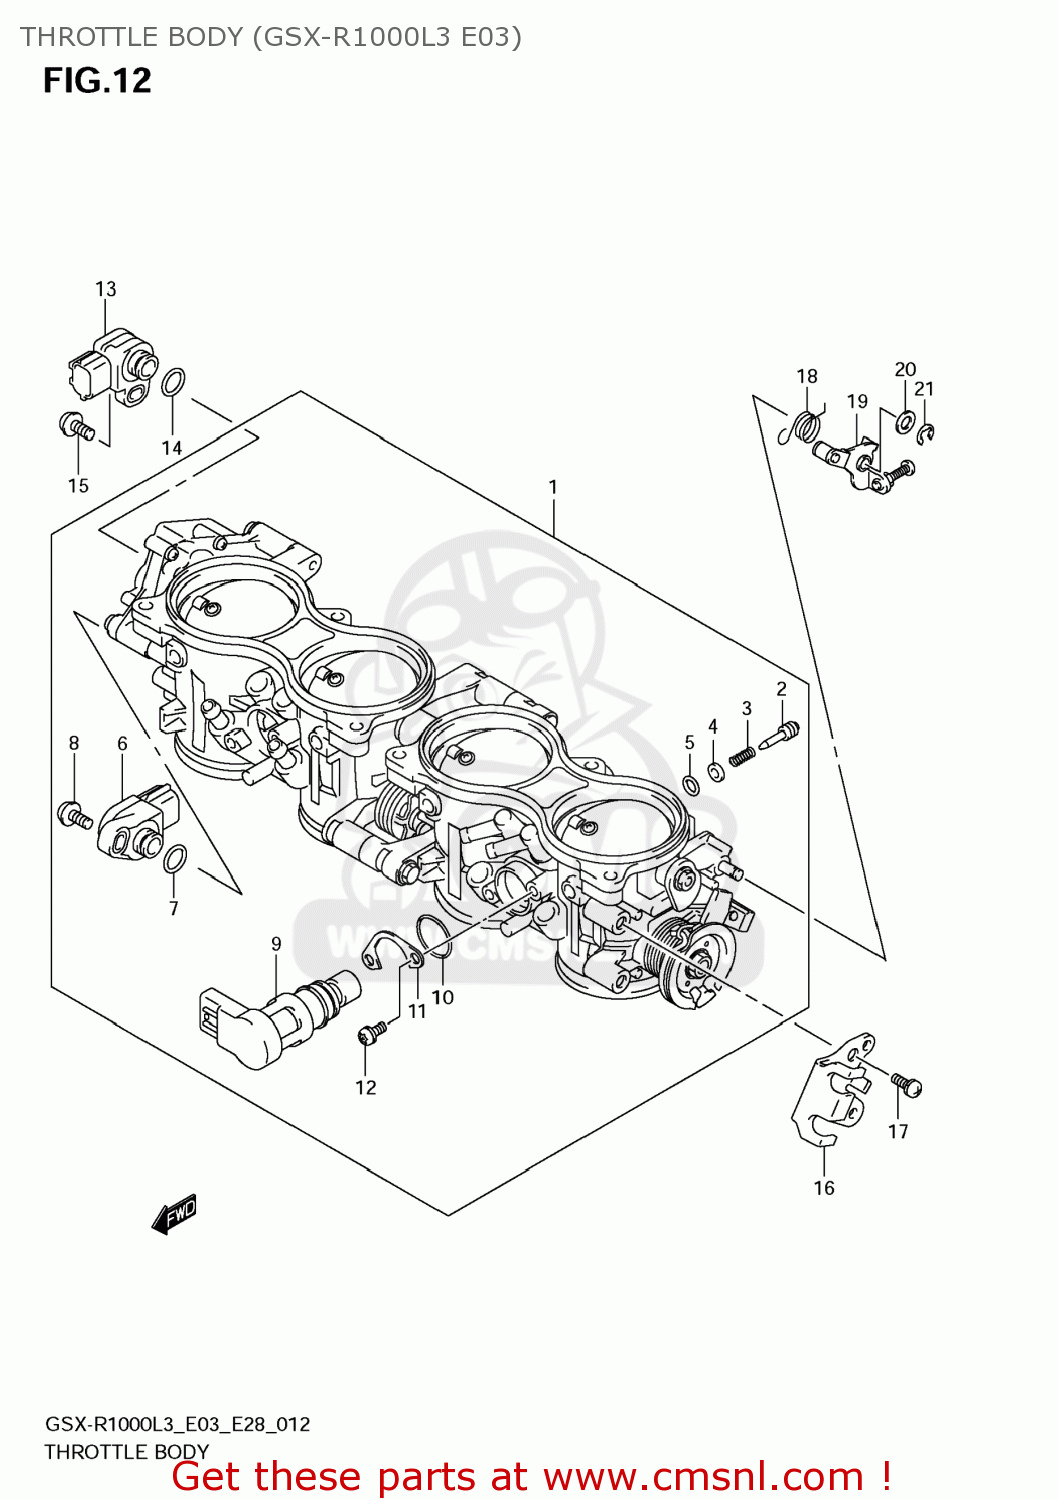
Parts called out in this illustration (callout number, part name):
1	BODY ASSY,THROTTLE
2	SCREW,AIR ADJUST
3	SPRING
4	WASHER
5	O RING
6	SENSOR ASSY,THROTTLE MAIN
7	O RING
8	SCREW
9	VALVE ASSY,ISC
10	O RING
11	PLATE,ISC VALVE
12	SCREW
13	SENSOR ASSY,THROTTLE SUB
14	O RING
15	SCREW
16	PLATE,STAY
17	SCREW
18	SPRING
19	LEVER ASSY,LINK
20	WASHER
21	E CLIP
